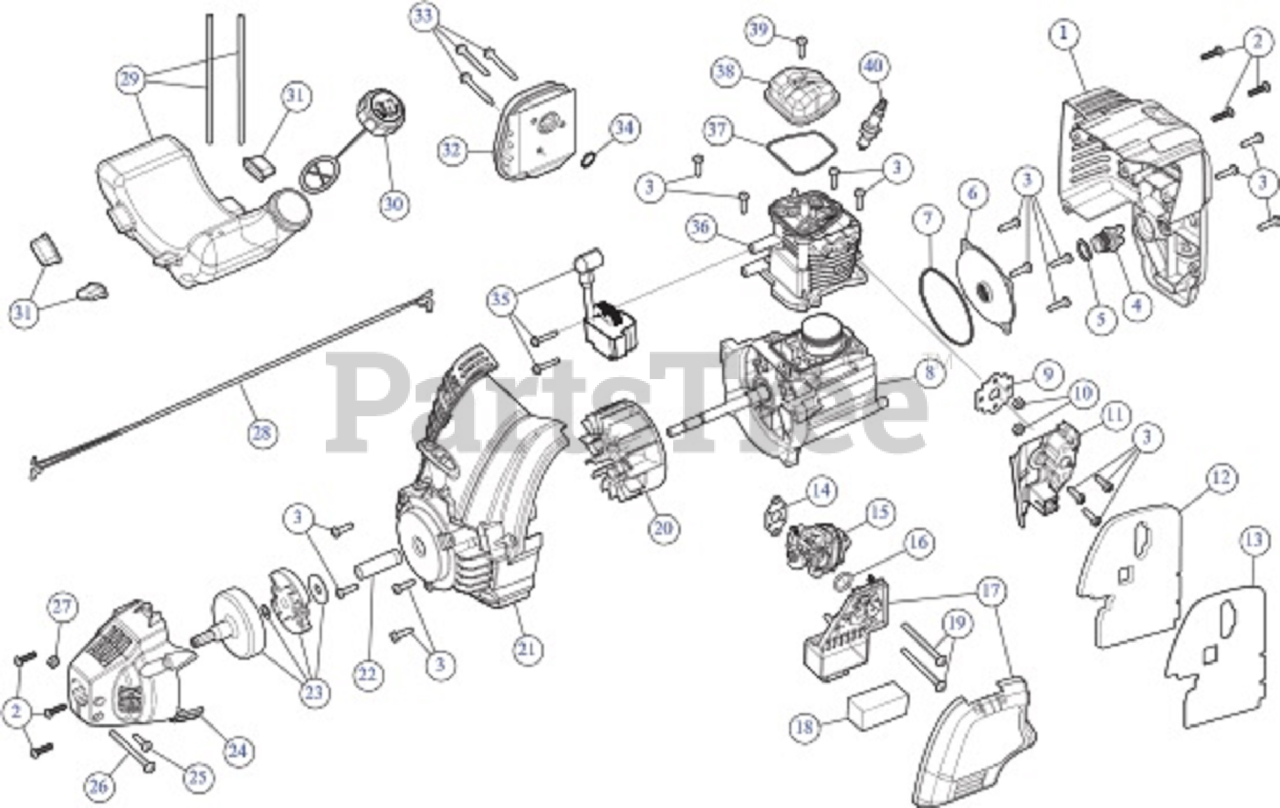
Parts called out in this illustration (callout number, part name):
1	Engine Cover Assembly (Incl. 2 & 3)
2	Cover Screw
4	Oil Plug (Incl. 5)
5	Oil Plug O-Ring
6	Crankcase Cover
7	Crankcase Cover O-Ring
8	Crankcase Assembly (Incl. 7)
9	Insulator Gasket
12	Heat Shield
13	Carburetor Gasket
15	Carburetor
17	Air Cleaner Cover Assembly (Incl. 18)
18	Air Filter
20	Flywheel Assembly
21	Starter Housing Assembly (Incl. 3)
22	Powershaft Spacer
23	Clutch Assembly
24	Clutch Cover (Incl. 2)
25	Anti-Rotation Screw
26	Clamp Screw
28	Lead Wires
29	Fuel Tank Assembly w/Fuel Lines (Incl. 30)
30	Fuel Tank Cap
31	Fuel Tank Pads
32	Muffler Assembly (Incl. 33 & 34)
33	Muffler Screw
34	Muffler Gasket
35	Module Assembly
36	Cylinder Assembly
37	Rocker Cover O-Ring
38	Rocker Cover
39	Rocker Cover Screw
40	Spark Plug
